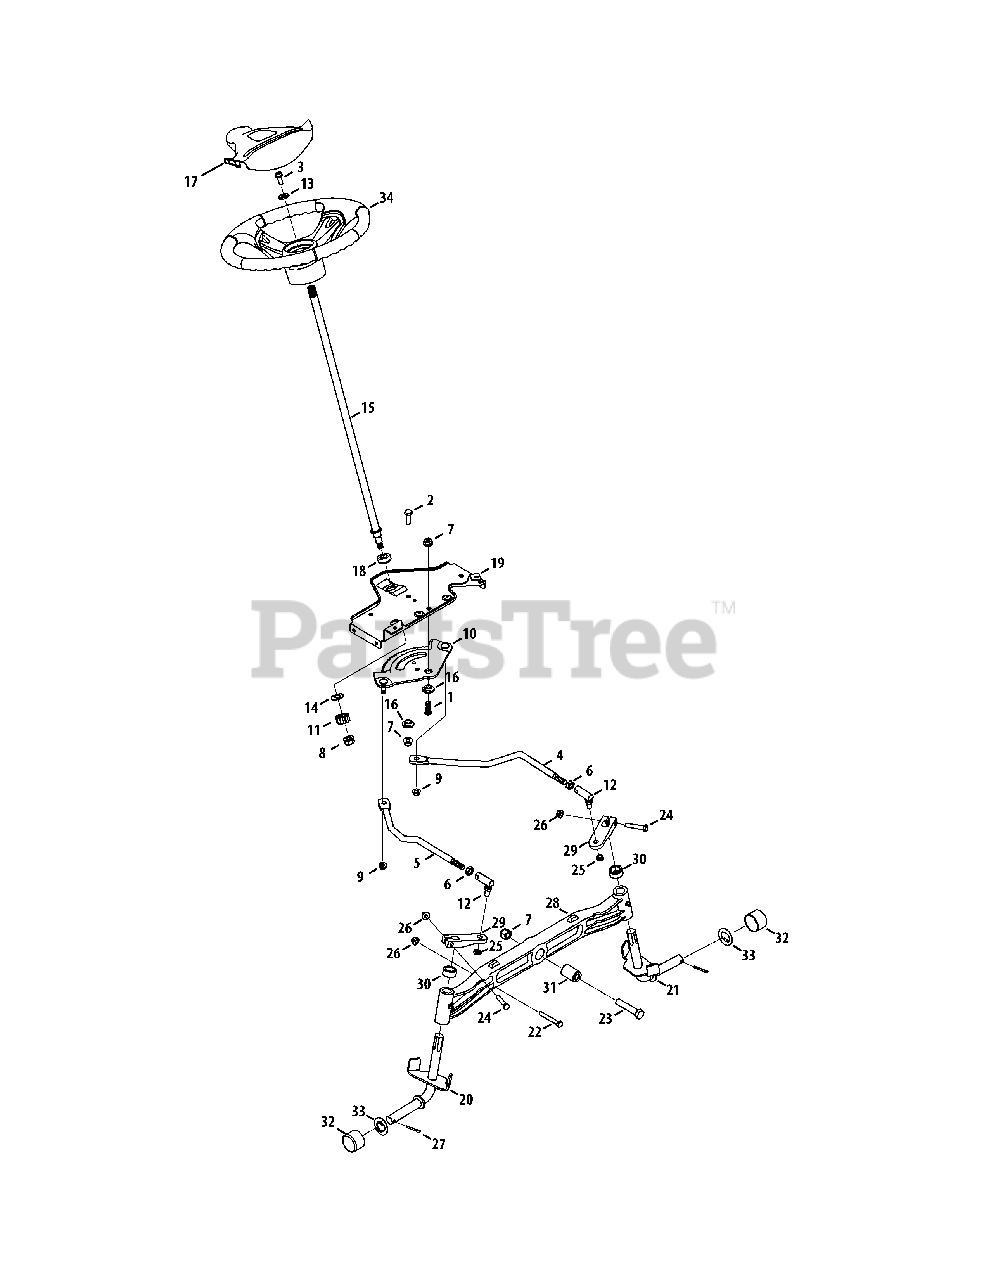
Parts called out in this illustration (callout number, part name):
1	Hex Screw, 3/8-16, 1.00, Gr5, Spec
2	Hex Screw, 3/8-16, 1.00, Gr5, Std
3	Hex Screw, 5/16-18, .875, Gr5, Lock
4	Link, Drag LH
5	Link, Drag RH
6	Nut, Jam, 7/16-20, Gr2
7	Nut, Flange Lock, 3/8-16, Grf,
8	Nut, Flange Lock, 7/16-20, Grb, Lock
9	Nut, Flange Lock, 5/16-18, Gr5, Sd Lk
10	Gear, Steering, 11/90 Ratio
11	Gear, Pinion, Steering
12	Ball Joint, 7/16-20, Lock
13	Washer, Flat, .406 x .875 x .105
14	Washer, Flat, .51 x 1.12 x .06
15	Shaft, Steering, .625 OD x 25, Cub
16	Spacer, Shoulder, .385x 1.25 x .3025
17	Cover, Steering Wheel, Cub Cadet
18	Bearing, Flange, Hex 5/8 Pm
19	Bracket, Support, Steering
20	Axle Ass’y, RH .750 Dia. (42" Deck)
20	Axle Ass’y, RH .750 Dia. (46" Deck)
21	Axle Ass’y, LH .750 Dia. (42" Deck)
21	Axle Ass’y, LH .750 Dia. (46" Deck)
22	Hex Screw, 5/16-18, 2.25, Gr5, Std
23	Hex Screw, 3/8-16, 2.50, Gr5, Std
24	Hex Screw, 5/16-18, 1.75, Gr5, Std
25	Nut, Hex Lock, 3/8-24, Grb
26	Nut, Flange Lock, 5/16-18, Grf
27	Pin, Cotter, 5/32, 1.25
28	Axle, Pivot Bar, Cast
29	Steering, Block
30	Spacer, .71 ID x .125 OD x .56
31	Spacer, .385 x 1.00 x 1.5075
32	Cap, Bumper
33	Washer, Flat, .350 x 1.559 x .062
34	Wheel, Steering, 3 Spoke, Softgrip
